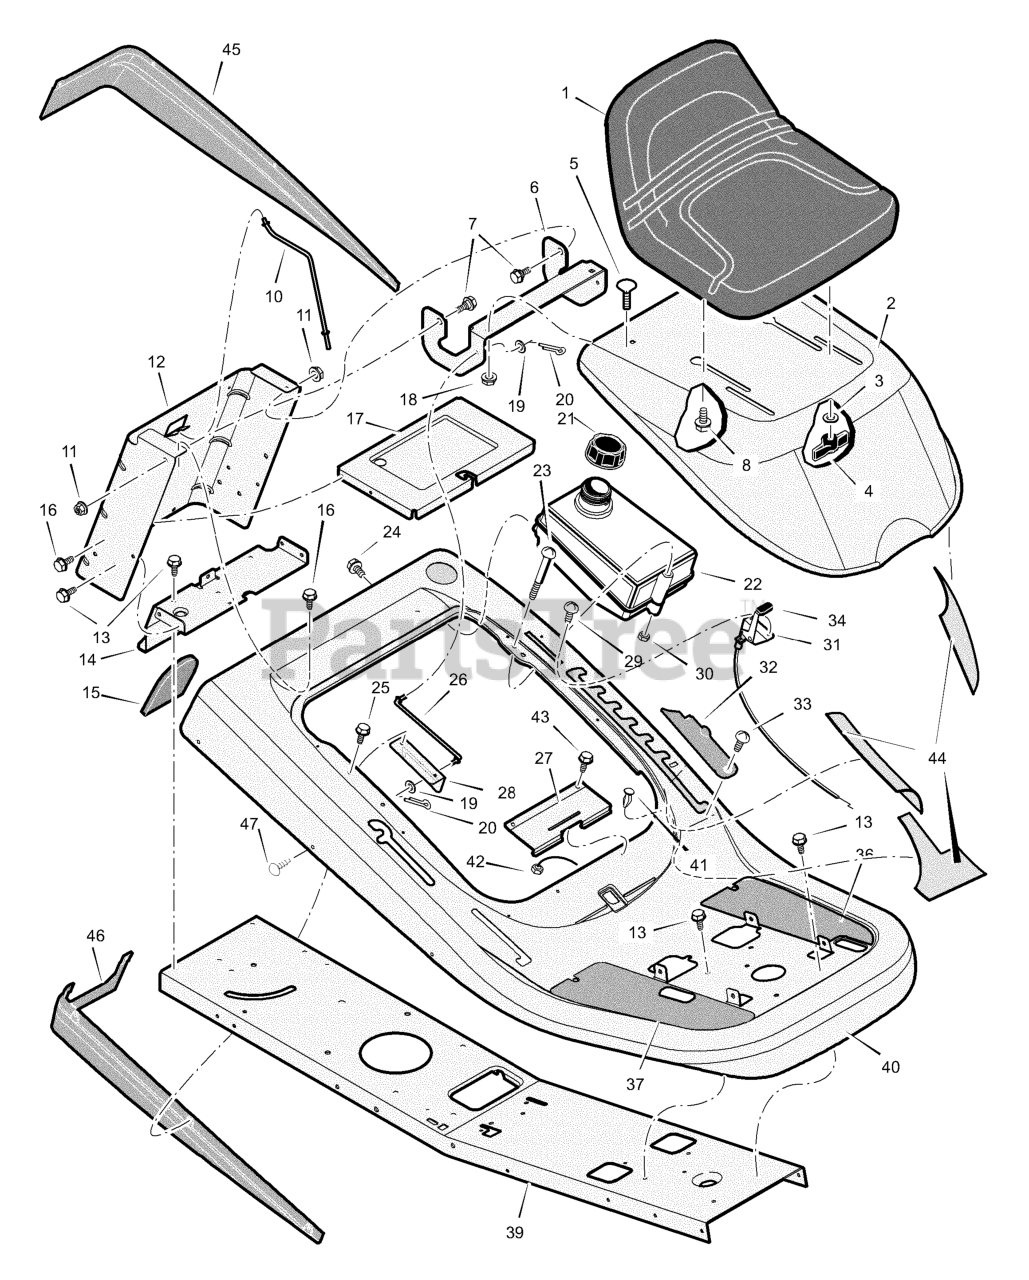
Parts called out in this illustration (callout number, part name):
1	Seat
3	Washer
4	Bolt, Wing
5	Bolt, Carriage
6	Bracket, Hinge
7	Bolt, Shoulder
8	Bolt, Shoulder
10	Rod, Battery
11	Nut, Flange
12	Plate, Rear
14	Plate, Hitch
17	TRAY, Battery
18	Nut, Flange
19	Washer
20	Pin, Cotter
21	Cap, Fuel Tank
22	Tank, Fuel
23	Screw
26	Rod, Hood Prop
27	Spring, Seat Deck
28	Bracket, Prop Rod
30	Nut, NY-Lock
31	Control, Throttle
32	Cover, Detent (Black)
33	Bolt, Shoulder
36	Footmat, Left (Black)
37	Footmat, Right (Black)
40	Deck, Seat
41	Bumper
42	Nut
43	Screw
44	Kit, Foil Heat Shield
45	Trim, Left
46	Trim, Right
47	Fastener, Panel
